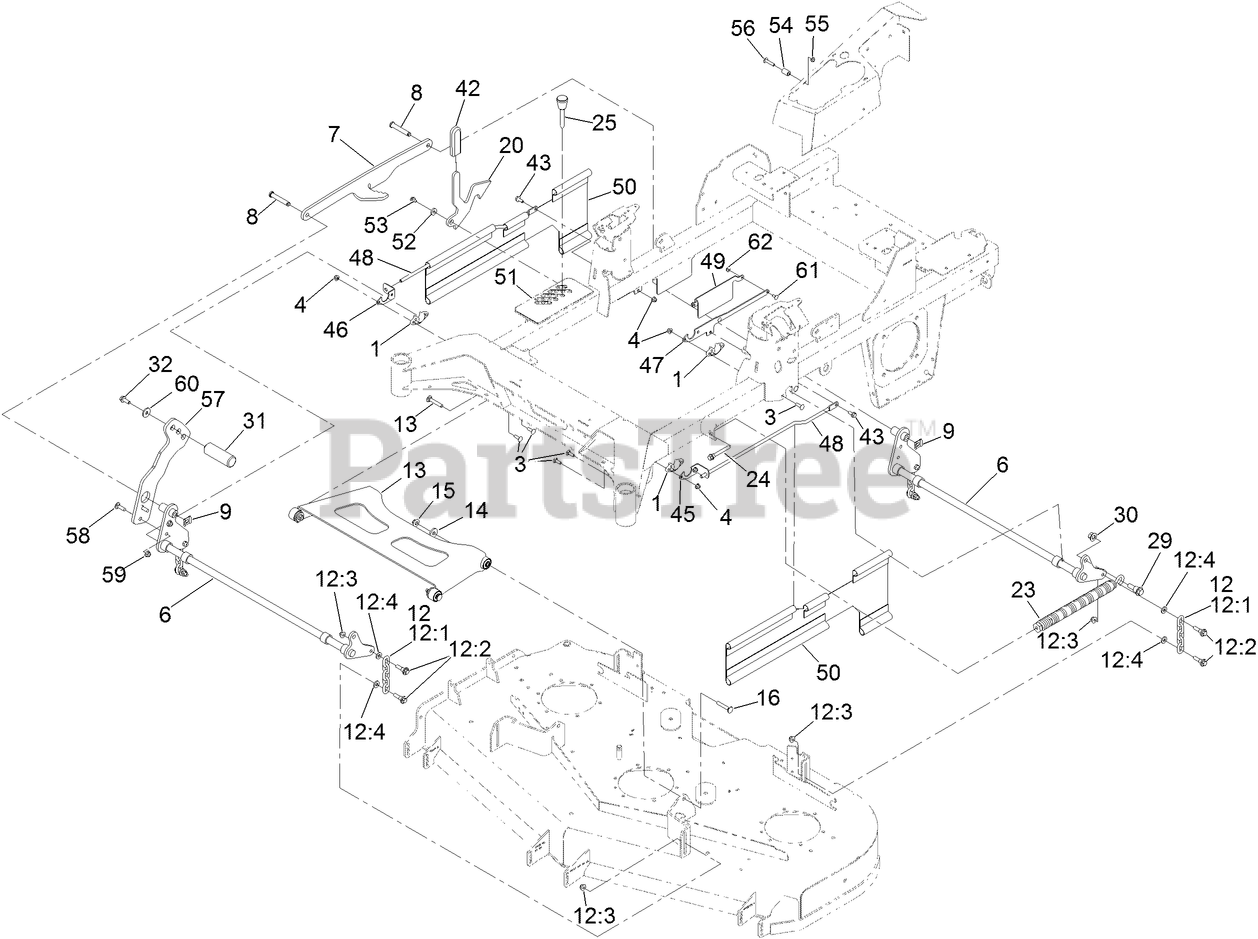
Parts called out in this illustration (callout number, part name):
1	BUSHING-FLANGE
3	SCREW-CARR
4	NUT-HF, NI
6	DECK LIFT SHAFT ASM [BLACK]
7	LINK-LIFT
8	PIN-CLEVIS
9	CLIP-PIN
12	DECK CHAIN ASM
12:1	CHAIN-LIFT, DECK
12:2	BOLT-SHOULDER
12:3	NUT-HF, NI
12:4	SPACER
13	ASM-DECK STRUT W/ BUSHINGS
14	WASHER
15	NUT-FLANGE, NI
16	SCREW-CARR
20	PLATE-TRANSPORT LOCK
23	SPRING-EXTENSION
24	BOLT-SHOULDER
25	PIN-HOC
29	SCREW-SHOULDER, HHF
30	NUT-LOCK
31	PEDAL-FOOT LIFT
32	SCREW-HHF
42	GRIP-LEVER
43	SCREW-HHF
45	BRACKET-MOUNT, UPPER FRONT (LH)
46	BRACKET-MOUNT, UPPER FRONT (RH)
47	BRACKET-MOUNTING, UPPER
48	ROD-SUPPORT, UPPER
49	BRACKET-FLAG
50	GUARD-SIDE
51	DECAL-HOC, MM
52	SPACER
53	SCREW
54	SPACER
55	NUT-LOCK, NI
56	SCREW-TORX
57	ARM-DECK LIFT [BLACK]
58	BOLT-CARR
59	NUT-HF, NI
60	WASHER
61	SCREW-CARR
62	NUT-HF
